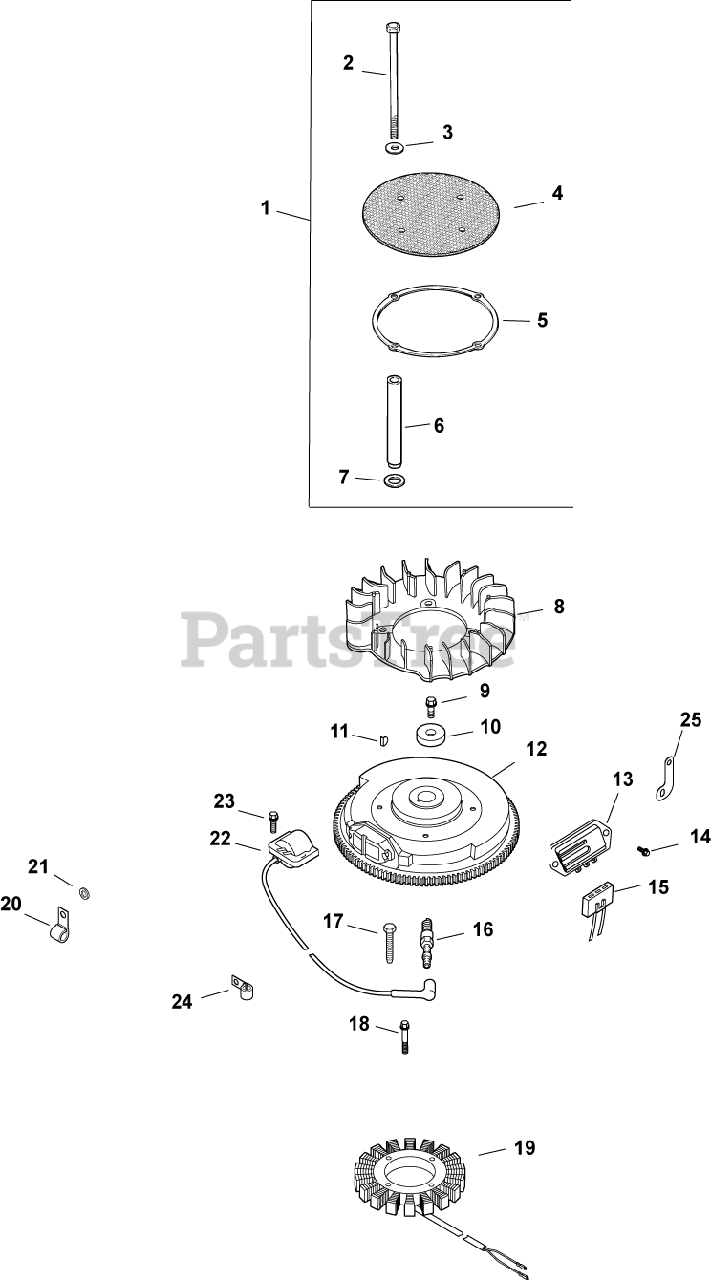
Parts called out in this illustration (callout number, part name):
1	KIT, CHOPPER SCREEN
2	SCREW, CAP M6X1.0X99.5
3	WASHER, FLAT 1/4" (O.D. 5/8")
4	SCREEN, GRASS
5	RING, SUPPORT USE 25 141 08-S
7	WASHER, SPRING 10 MM
9	SCREW, FLG M10X1.5X45 - (#25086361S)
10	WASHER, FLAT 13/32"
11	KEY, 3/16" X 5/8"
12	FLYWHEEL ASSEMBLY (LW)
13	REGULATOR/RECTIFIER
14	SCREW, HEX FLANGE HI-LO
15	CONNECTOR
16	PLUG, SPARK (STD)
17	SCREW, M5X0.8X25 - (#25086402S)
18	SCREW, SKT SET #10-24X1/4"
19	KIT, 15 / 20 AMP STATOR
20	CLIP, CABLE
21	WASHER, FLAT 1/4" (O.D. 1/2")
22	MODULE, IGNITION
23	SCREW, FLG THD FRM M5X.8X20-(#25086399S)
25	BRACKET, GROUND STRAP USE 24 518 12-S
2458452-S	MODULE, SPARK ADV -USE 24 584 89-S
